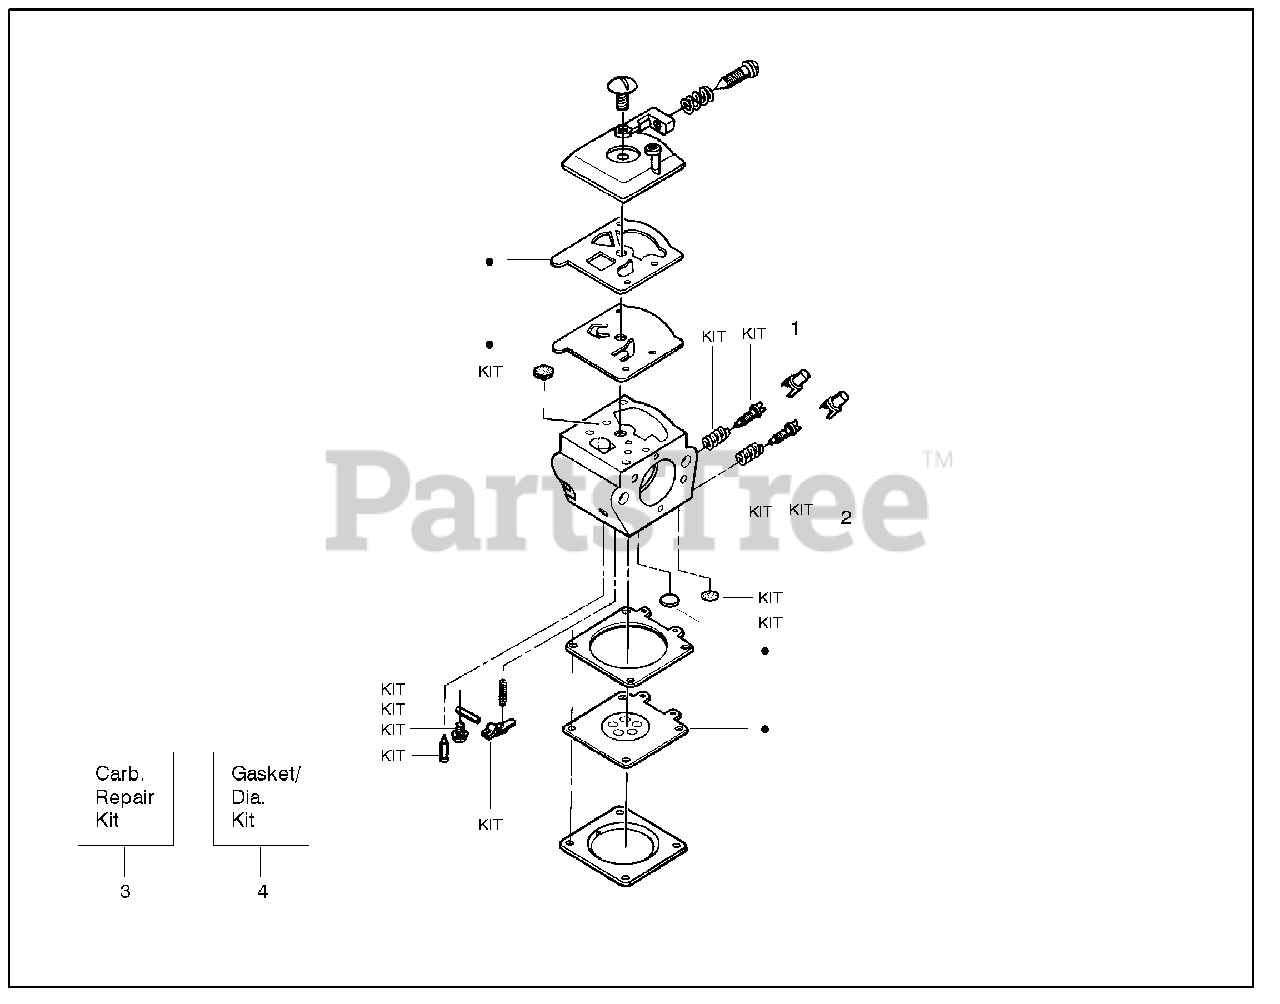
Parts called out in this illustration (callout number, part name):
1	Limiter Cap-High
2	Limiter Cap-Low
3	Carburetor Repair Kit
4	Gasket Diaphragm Kit
